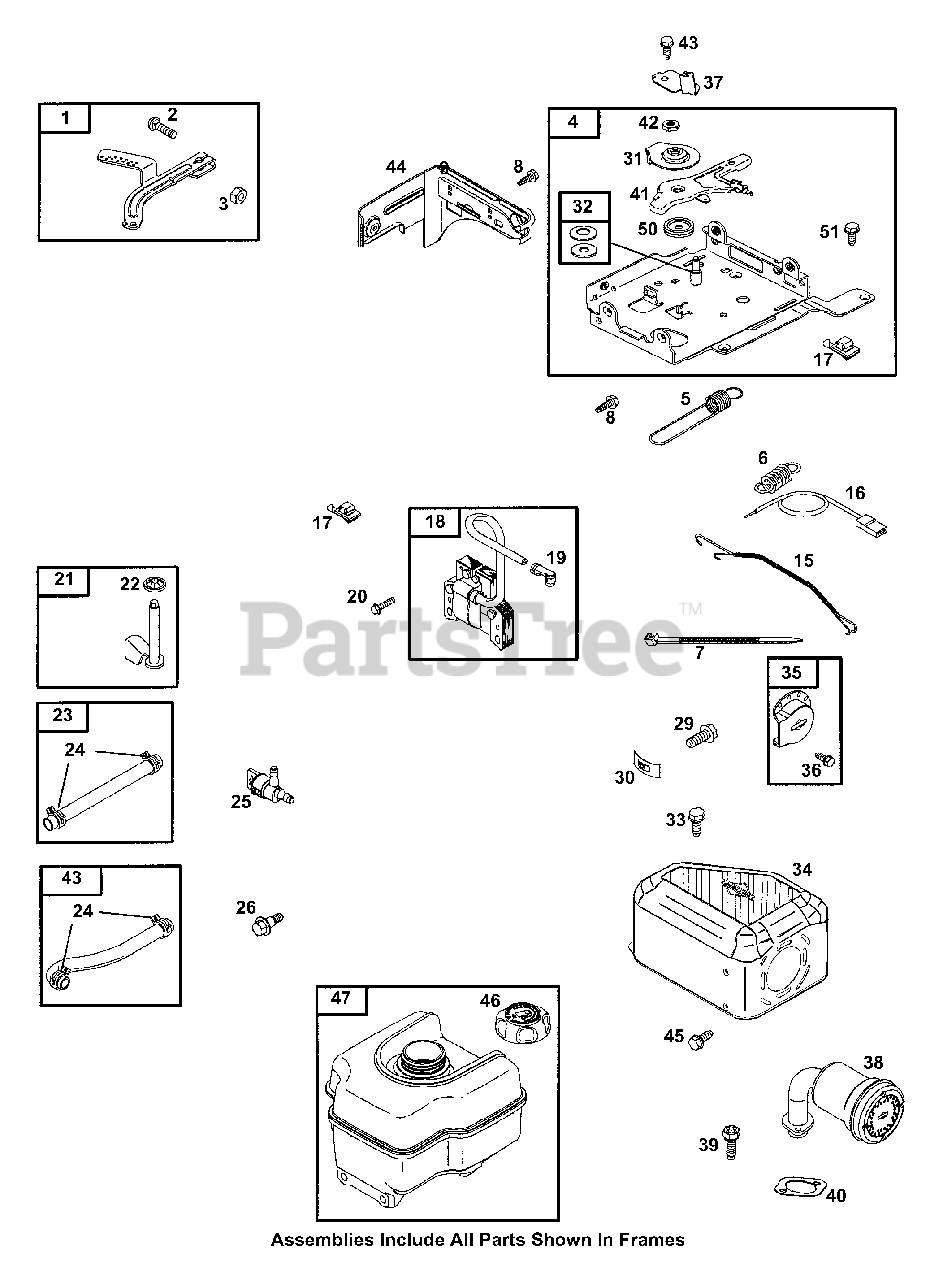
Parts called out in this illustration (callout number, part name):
1	Governor Lever
2	Bolt (Governor Control Lever)
3	Nut (Governor Control Lever)
4	Control Brkt
5	Governor Spring
6	Governor Spring
8	Screw (Control Panel)
15	Spring/Link (Mechanical Governor)
17	Switch-Stop
18	Armature-Magneto
19	Sparkplug Terminal
20	Screw (Magneto Armature)
21	Crank-Governor
22	Governor Shaft Retainer
23	Fuel Line
24	Clamp-Hose
25	Fuel Shutoff Valve
26	Screw (Fuel Tank)
29	Screw (Fuel Tank)
31	Retainer
32	Washer Set
33	Screw (Muffler Guard)
34	Muffler Guard
35	Muffler Deflector
36	Screw (Muffler Deflector)
37	Fixed Brkt
38	Exhaust Muffler
39	Screw (Exhaust Muffler)
40	Exhaust Gasket
41	Control Lever
42	Nut (Control Brkt)
43	Fuel Line (Molded)
44	Control Panel
45	Screw (Muffler Guard)
46	Fuel Tank Cap
47	Fuel Tank
